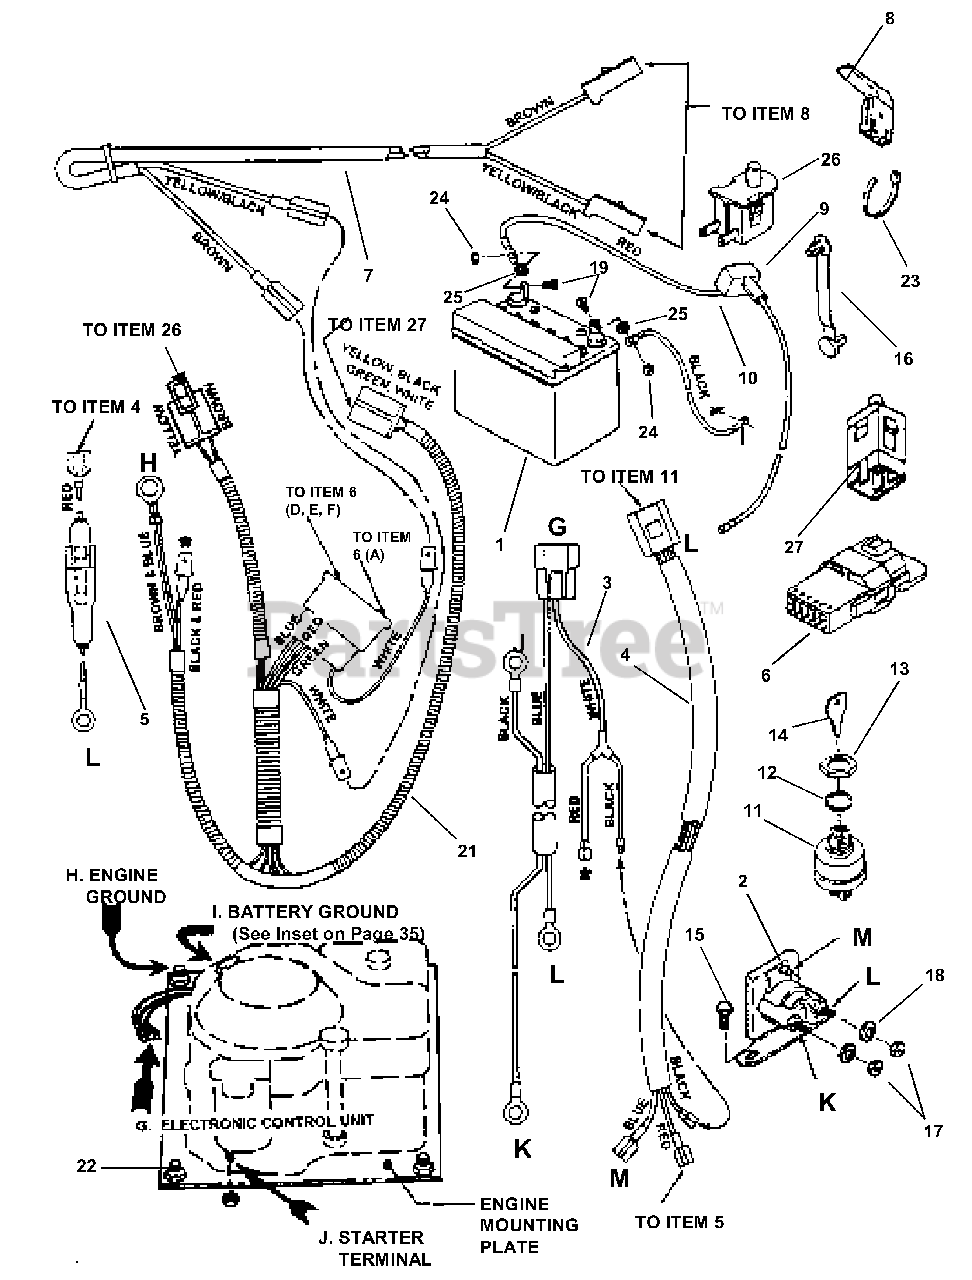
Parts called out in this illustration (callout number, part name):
1	KIT, Battery, 12V, U-1-7RS, 220CCA Dry Charge Snapper No Spill
2	SOLENOID
3	HARNESS, Starter Wiring (Kohler)
4	HARNESS, Ignition Wiring (Kohler)
5	HOLDER, Fuse
6	INTERLOCK Module (Briggs & Kohler)
7	HARNESS, (Deck Interlock Wiring)
8	SWITCH, Deck Interlock (NO)
9	COVER, Battery Cable
10	CABLE, Positive (Red) (17" Long)
11	SWITCH, Ignition
12	WASHER, 5/8 Internal Tooth Lock
13	NUT, 5/8-32 Hex
14	KEY, Switch
15	SCREW, 1/4-20 x 1/2" Hex Washer Self-Tap
16	TIE, 2" Long Cable
17	NUT, 1/4-20 Hex
18	WASHER, 1/4 Internal Tooth Lock
19	SCREW, 1/4-20 x 5/8" Hex Head Cap, Grade 5
21	HARNESS, Operator Presence Control Wire
22	NUT, 1/4-20 Hex, Grade 5 or B
23	TIE, 7" Long Cable
24	NUT, 1/4-20 Hex Center Lock
25	RETAINER, 1/4 Bolt
26	SWITCH, Seat (NC)
27	SWITCH, Operator Presence Control (OPC) Traction (NC/NO)
